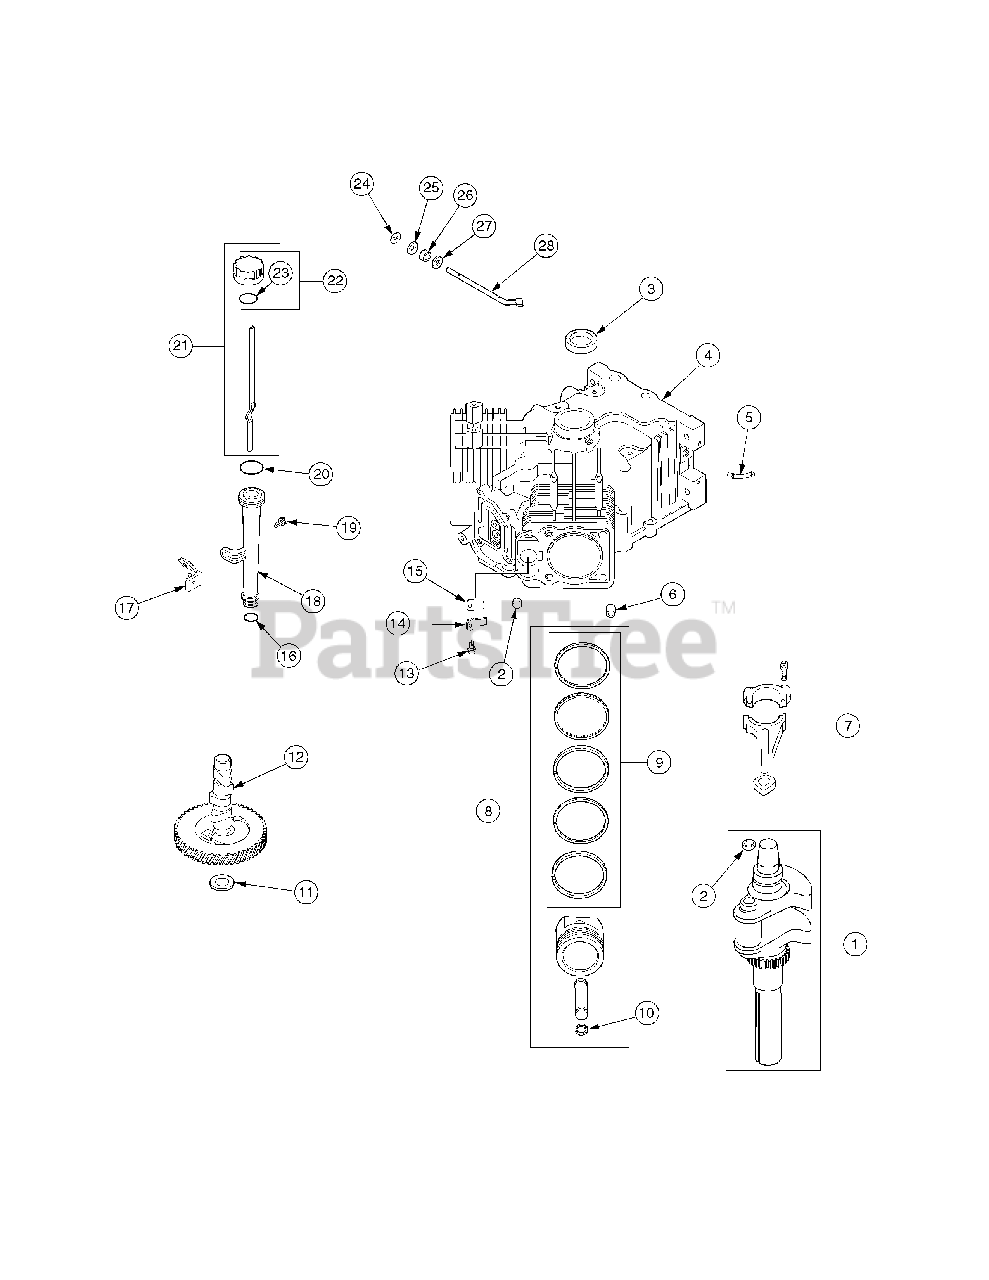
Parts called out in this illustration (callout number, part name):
1	Crankshaft
2	Plug, Cup
3	Seal, Front Oil
4	Crankcase, (Use Miniblock)
6	Pin, Locating Dowel
7	Rod, Connecting, Std
8	Piston w/Ring Set, Std
9	Ring Set, Std., .08
10	Retainer, Piston Pin
11	Shim, Camshaft, .0320 (Red)
12	Camshaft Assembly
13	Screw, Hex Flng, M5 x 0.8 x 10
14	Retainer, Breather Reed
15	Reed, Breather
17	Bracket, Oil Fill Tube
18	Tube, Oil Fill
19	Screw, Hex Flange, M5 x .8 x 16
20	O-Ring, Upper Oil Fill Tube
21	Dipstick Assembly
22	Kit, Oil Fill Cap
23	O-Ring, Dipstick
24	Ring, Retainer
25	Washer, Nylon
26	Seal, Governor Cross Shaft
27	Washer, Plain
28	Shaft, Governor Cross
